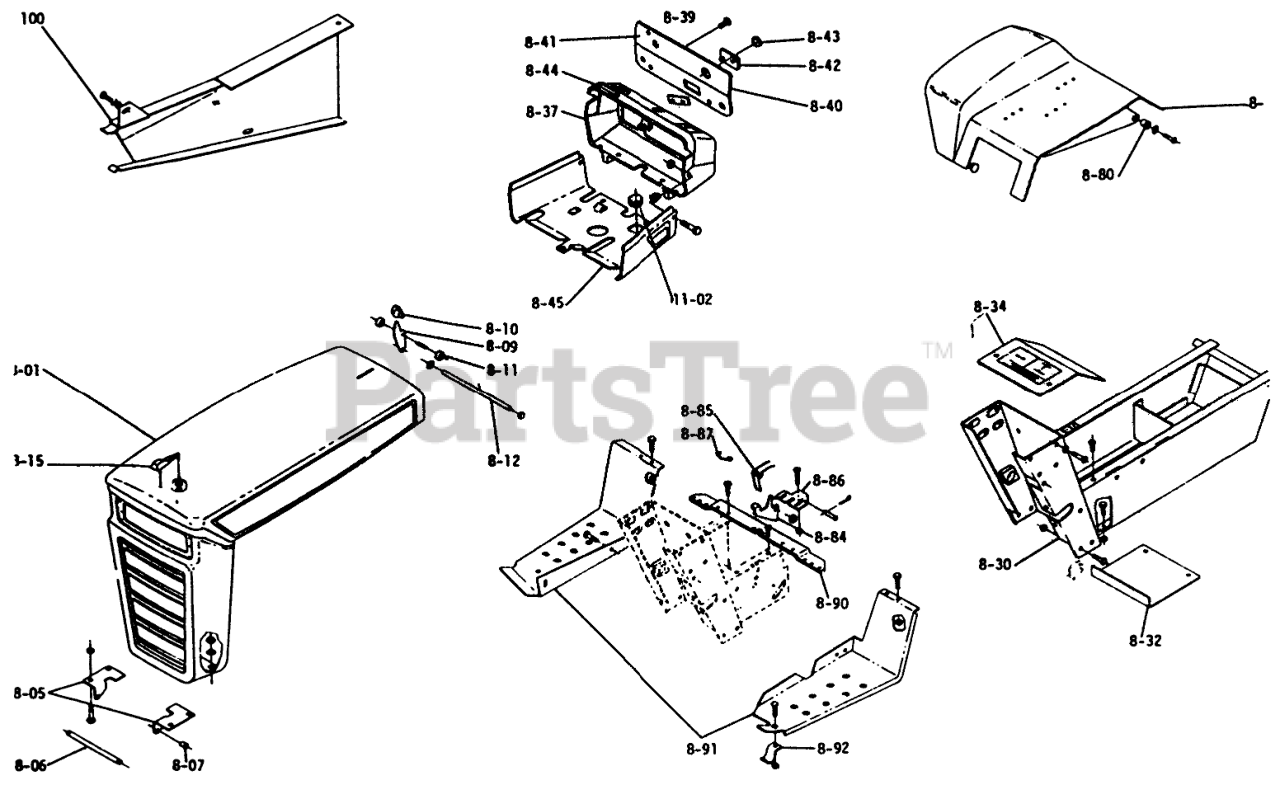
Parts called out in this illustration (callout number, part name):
8-07	NYLINER BUSHING
8-09	LEVER HOOD LATCH
8-10	KNOB
8-15	Hood Ornament
8-30	Assy-Hoodstand
8-32	Cover-Dust
8-39	Panel-Control
8-41	Plate-Support
8-80	BUSHING-FLANGED
8-85	Spring
8-87	Stop-Fender Latch
8-91	Footrest R.H.
8-92	BRACKET
